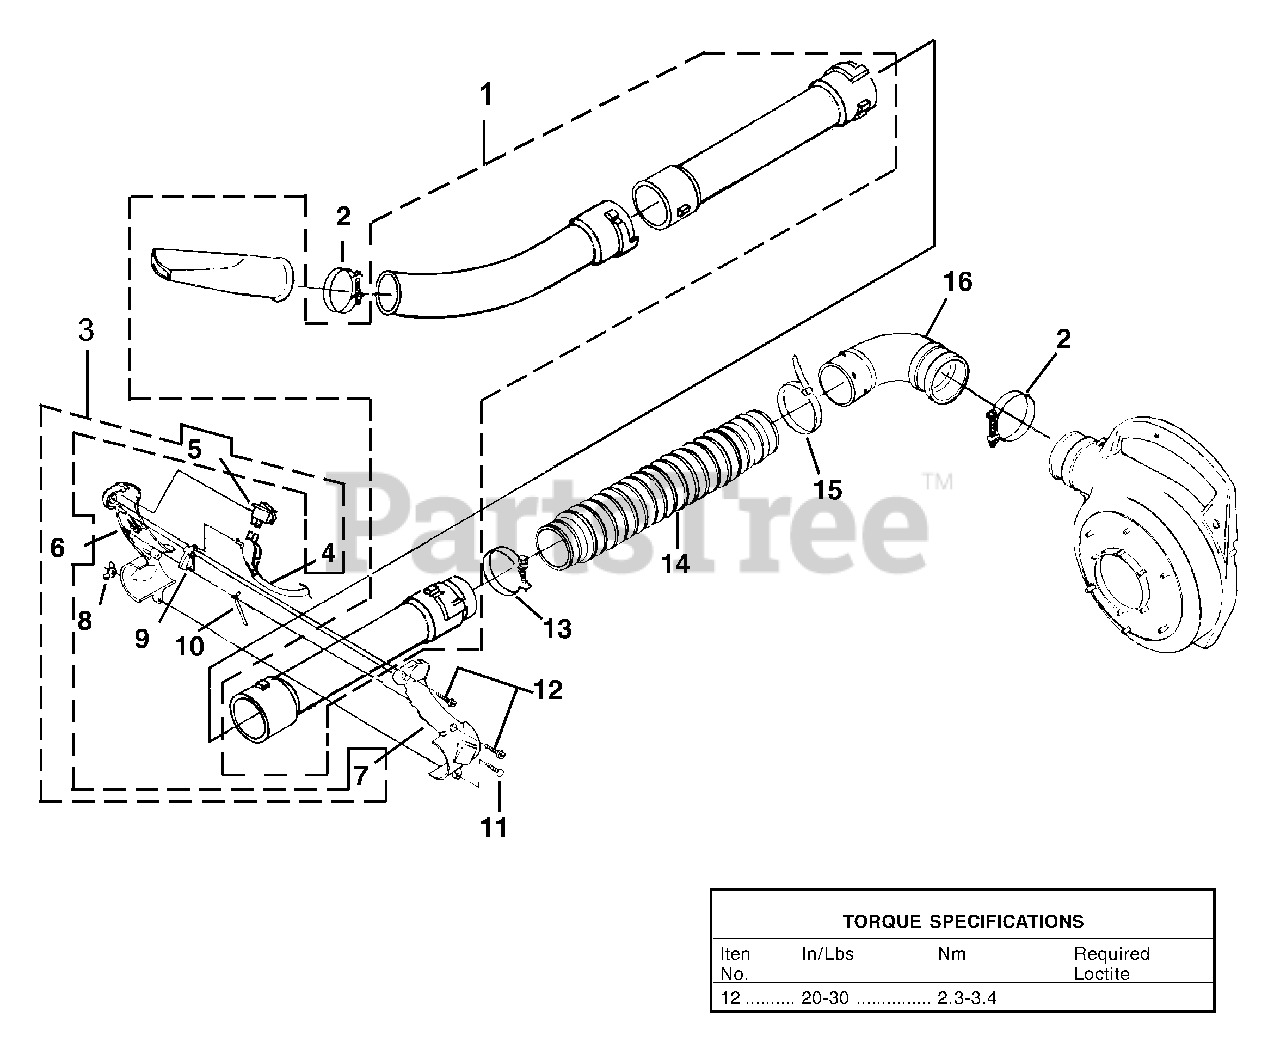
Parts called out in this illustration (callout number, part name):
1	BLOWER TUBE KIT
2	CLAMP
3	HANDLE & SWITCH KIT
4	CABLE-Throttle w/ Ignition Leads
6	HANDLE-Control (Right)
7	HANDLE-Control (Left)
8	NUT - Wing (10-24)
9	TRIGGER
10	LATCH-Trigger
11	BOLT-Rib Neck, Rnd. Hd. (10-24 X 7/8")
12	SCREW-Thread Form. (10-14 X 3/4")
13	CLAMP (#87)
14	BELLOWS-Plastic
15	CABLE-Tie
16	ELBOW-Curved
